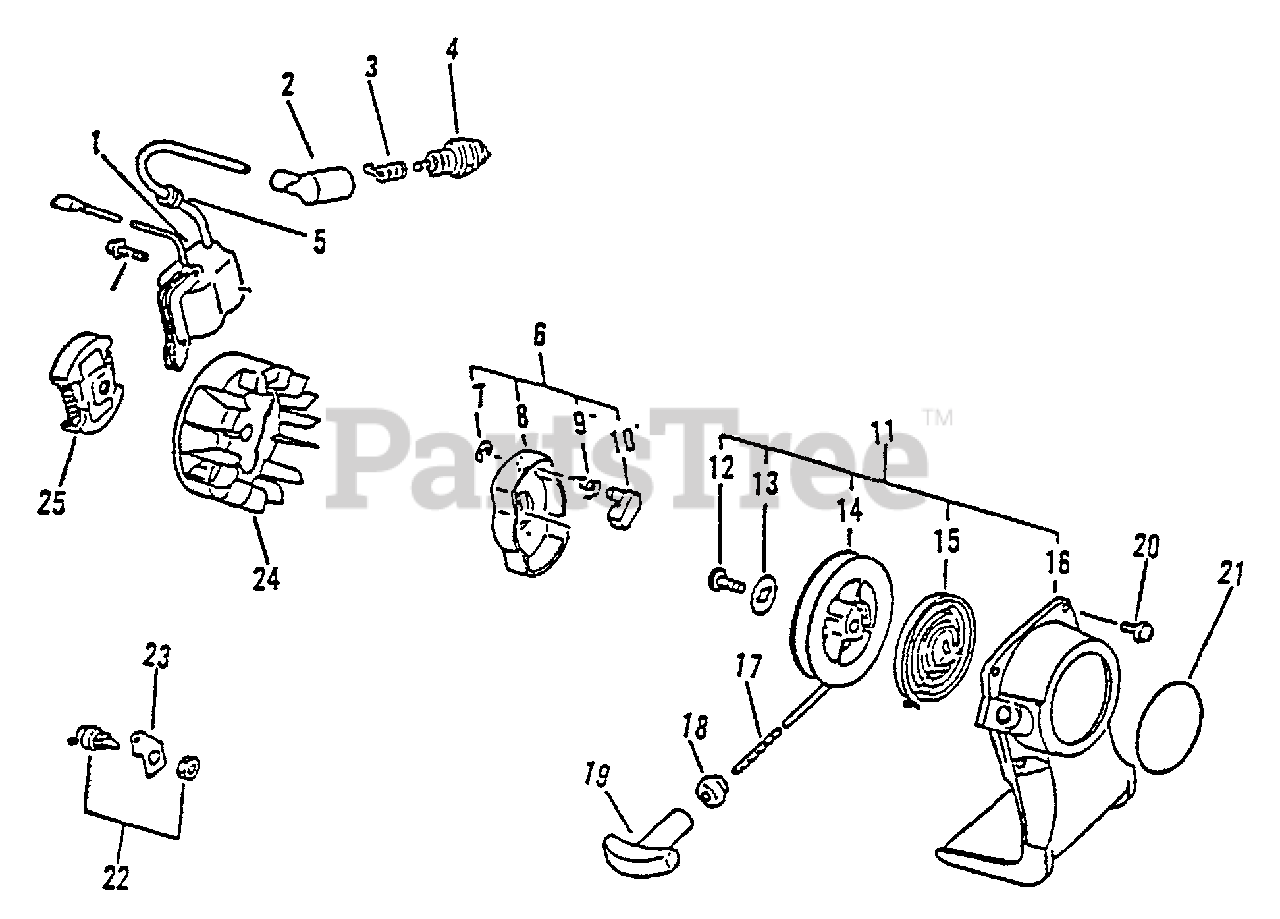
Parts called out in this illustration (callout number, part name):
1	COIL, IGNITION
2	CAP, SPARK PLUG
3	TERMINAL, SPARK PLUG CAP
4	SPARK PLUG -- BPM-7A
4	SPARK PLUG -- BPMR-7A
5	GROMMET
6	STARTER PAWL ASSY
7	RING, RETAINING - 4
8	CATCHER, PAWL
9	SPRING, RETURN
10	PAWL, STARTER
11	STARTER ASSY
13	WASHER
14	REEL, ROPE
15	SPRING, REWIND
16	CASE, STARTER - BLUE
17	ROPE, STARTER - 3X890
18	GUIDE, ROPE
19	GRIP, STARTER
20	SCREW - 4X16
21	LABEL - ECHO
22	IGNITION SWITCH ASSY
23	BRACKET, SWITCH
24	FLYWHEEL
25	CLUTCH ASSY
26	SCREW - 4X22
